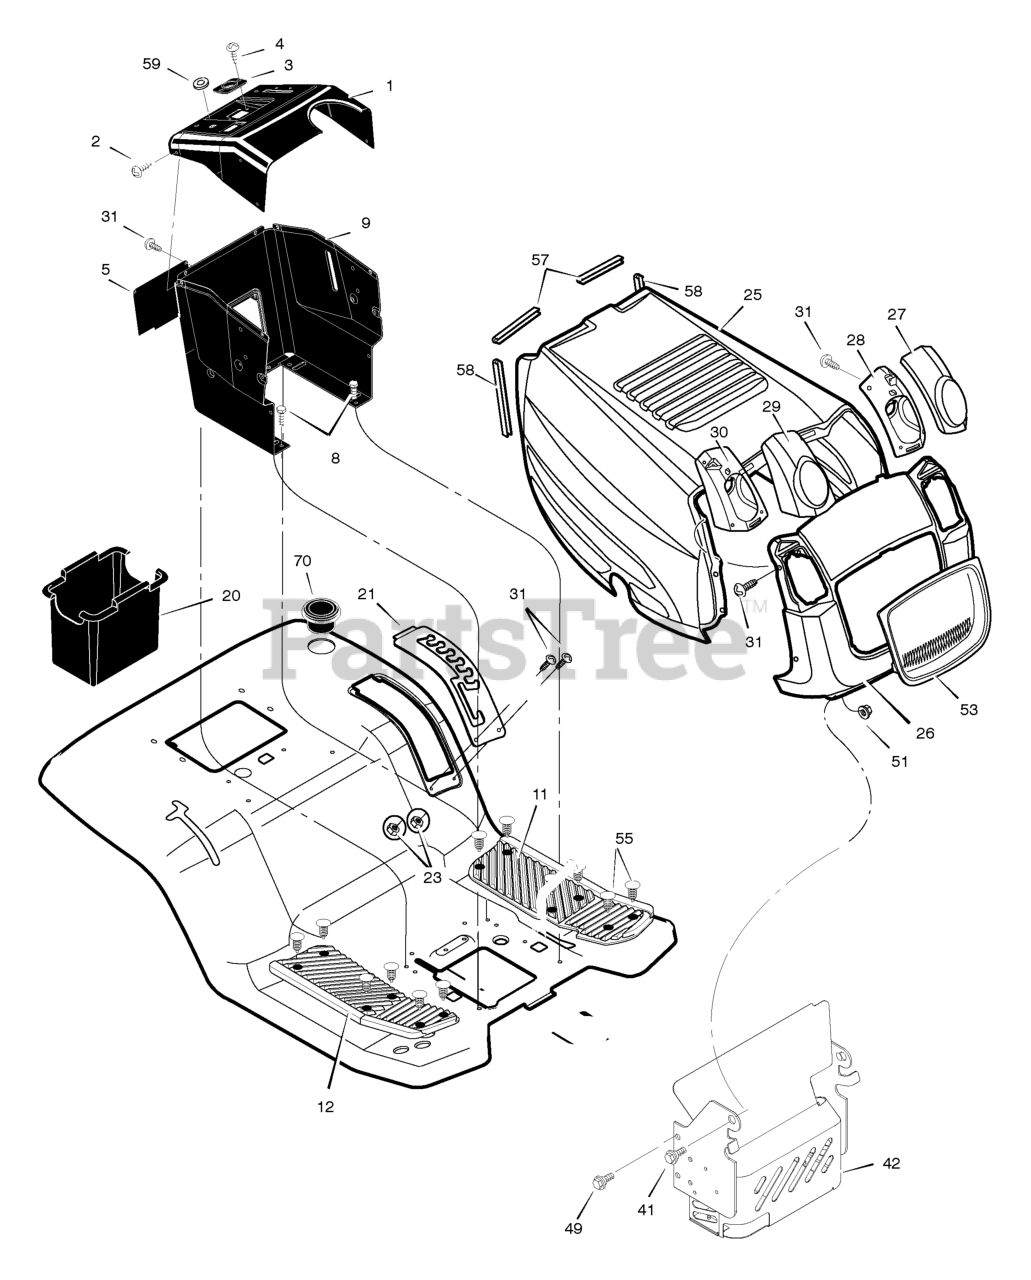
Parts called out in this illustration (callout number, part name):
3	Bearing, Upper Steering
5	Panel, Side Access
9	Support, Dash
11	Mat, Left
12	Mat, Right
20	Container, Battery
21	Plate, Lift Detent
25	Hood
27	Lens, Left
28	Housing, Left Headlamp
29	Lens, Right
30	Housing, Right Headlamp
31	Screw
41	Bolt
42	Shield, Heat
53	Insert, Grille
55	Fastener, Panel
57	Trim, Hood (3.75")
58	Trim, Hood (6.5")
59	Grommet, Parking Brake
70	Holder, Cup
